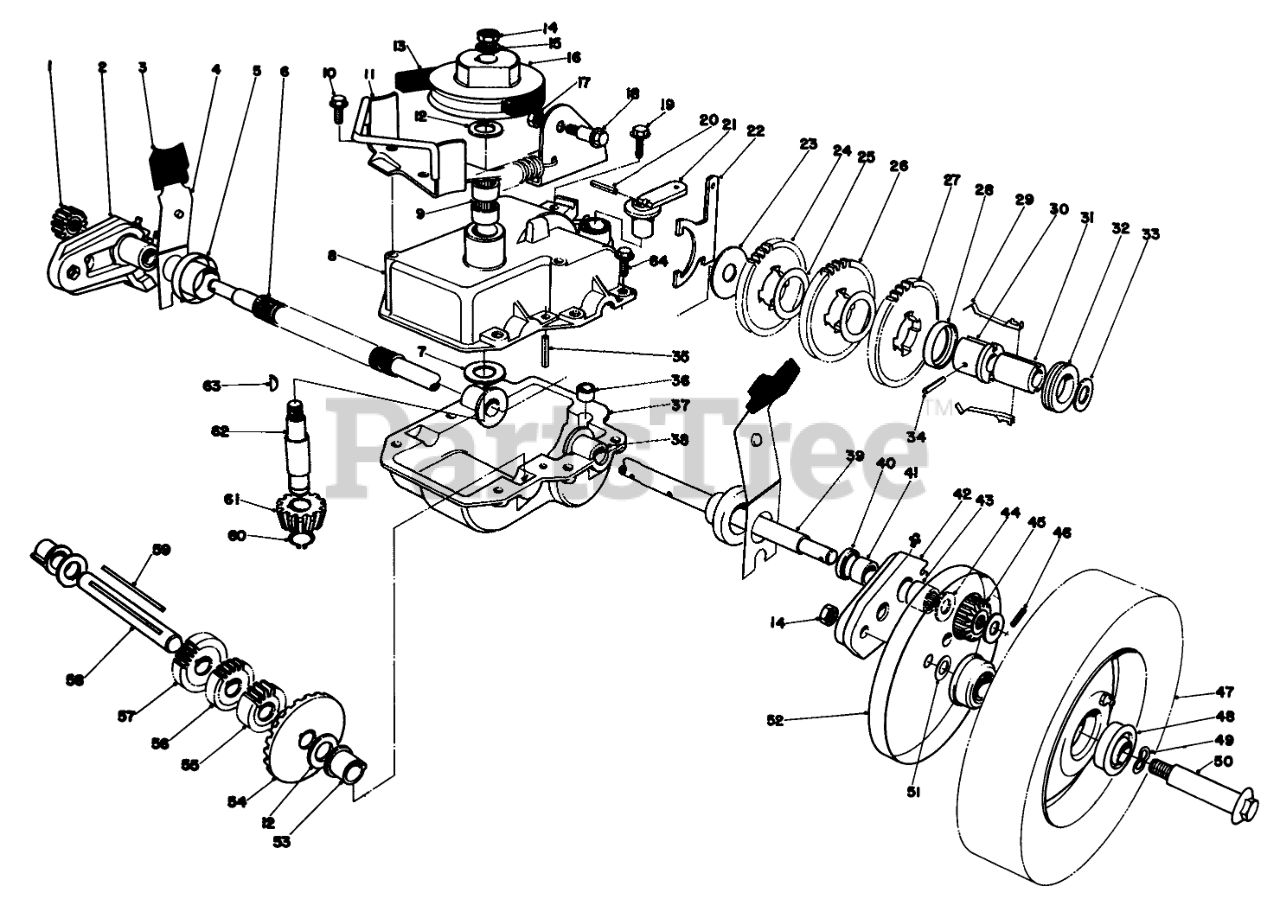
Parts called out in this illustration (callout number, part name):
1	RH CLUTCH & PINION
2	Pivot Arm R.H. (Incl. Ref. #40, 41 & 43)
3	KNOB-ARM
4	9520 Shift Yoke
5	End Cap
6	CONDUIT-CONVOLUTED, SPLIT
7	Thrust Washer
8	Upper Gear Case
9	Bearing
10	Screw
11	Belt Guide Bracket
12	WASHER-THRUST
13	V-BELT
14	Nut
15	WASHER-FLAT
16	Pulley
17	NUT-HEX, SIDE DEFORM
18	Shoulder Bolt
19	SCREW-HWHTF
20	PIN-COIL
21	LEVER-SHIFT
22	Shift Yoke
23	WASHER
24	Gear 35 Tooth
25	WASHER
26	Gear 37 Tooth
27	GEAR-42T
28	KEY RETAINER
29	KEY-SHIFT
30	Body-Sleeve
31	SLEEVE
32	COLLAR-SHIFT
33	WASHER-PLAIN
34	COIL PIN
35	ROLL PIN 3/16 X 1 IN
36	BUSHING-YOKE
37	LOWER GEAR CASE CAST
38	Bushing
39	OUTPUT SHAFT
40	Seal
41	Bushing
42	Pivot Arm L.H. (Incl. Ref. #40, 41 & 43)
43	Needle Baring
44	WASHER
45	LH CLUTCH & PINION
46	Pin
47	Wheel & Tire Assy. (Incl. Ref. #48)
48	BEARING-BALL
49	SPRING WASHER
50	WHEEL BOLT
51	WASHER
52	Cover-Wheel
53	Botching Shaft
54	BEVEL GEAR
55	14 T GEAR
56	Gear 19 Tooth
57	Gear 21 Tooth
58	Sort Shaft
59	Key Square
60	RING-RETAINING
61	PINION-BEVEL
62	Input Shaft & Pinion Assembly (Incl. Ref. #61)
63	KEY-WOODRUFF
64	SCREW-HWH, THREAD ROLL
